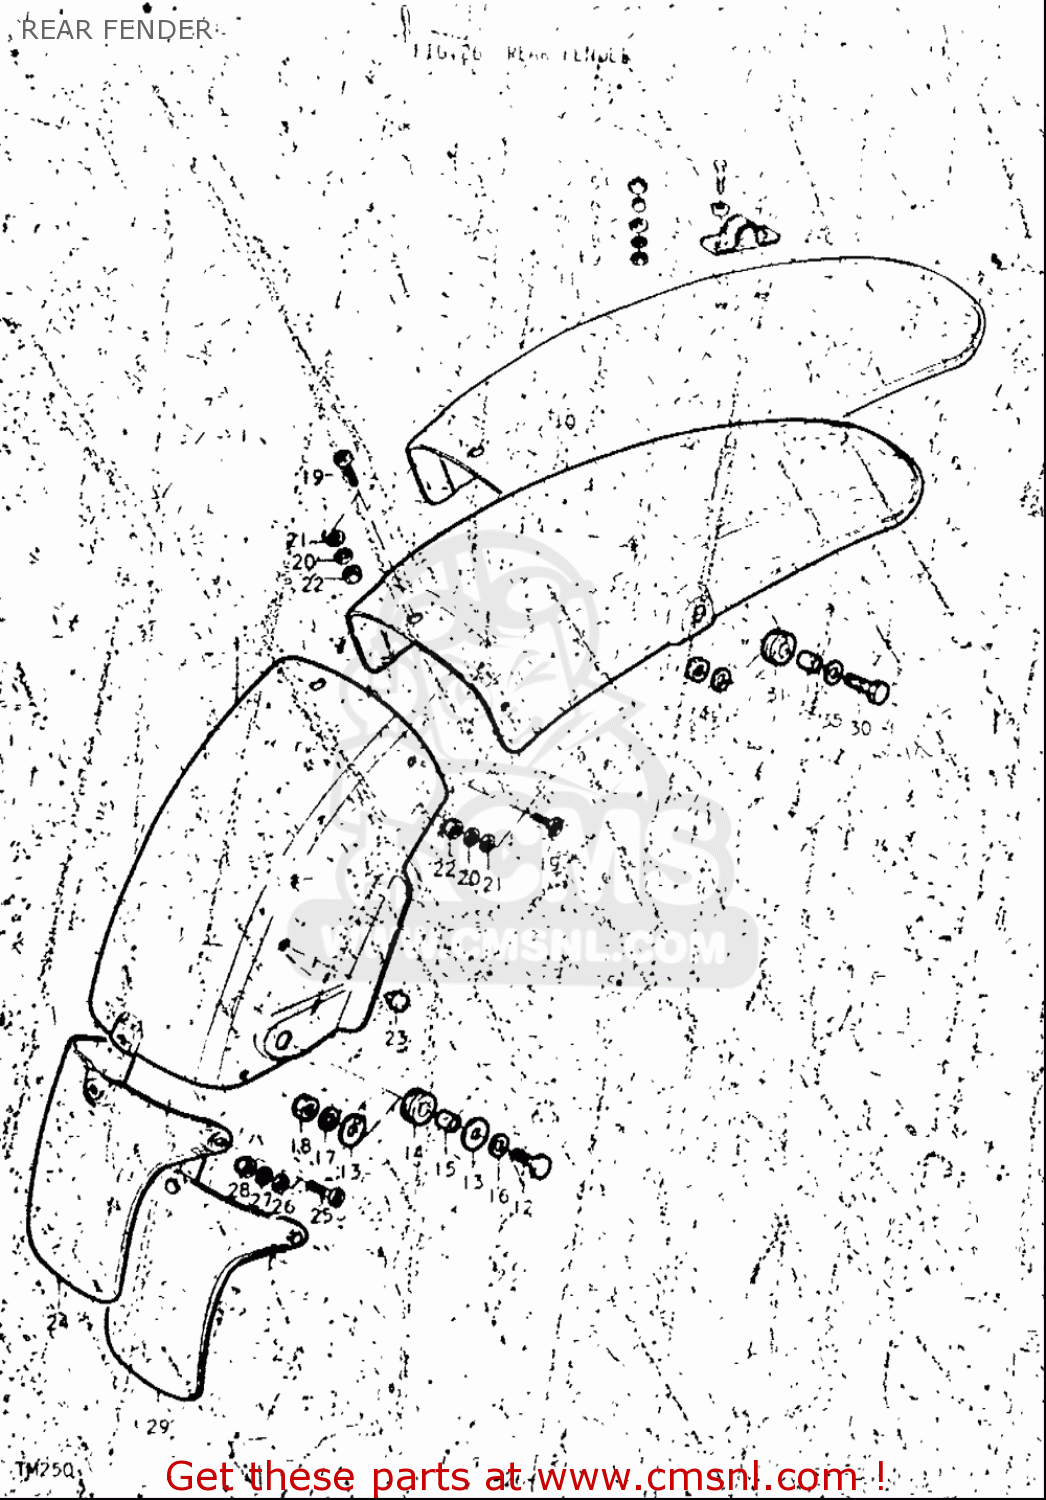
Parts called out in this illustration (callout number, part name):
3	BOLT(6X18)
4	WASHER
5	CUSHION
6	SPACER(6.5X10X7)
7	WASHER(6.5X20X1.2)
8	WASHER,LOCK
9	NUT
12	BOLT
13	WASHER(6.5X20X1.2)
14	CUSHION
15	SPACER(6.1X9X7.5)
16	WASHER
17	WASHER,LOCK
18	NUT
19	SCREW
20	WASHER,LOCK
21	WASHER
22	NUT
23	CUSHION
25	SCREW
26	WASHER,LOCK
28	NUT
30	BOLT
31	CUSHION
32	SPACER(6.1X9X7.5)
33	WASHER,LOCK
34	NUT
35	WASHER(6.5X20X1.2)
